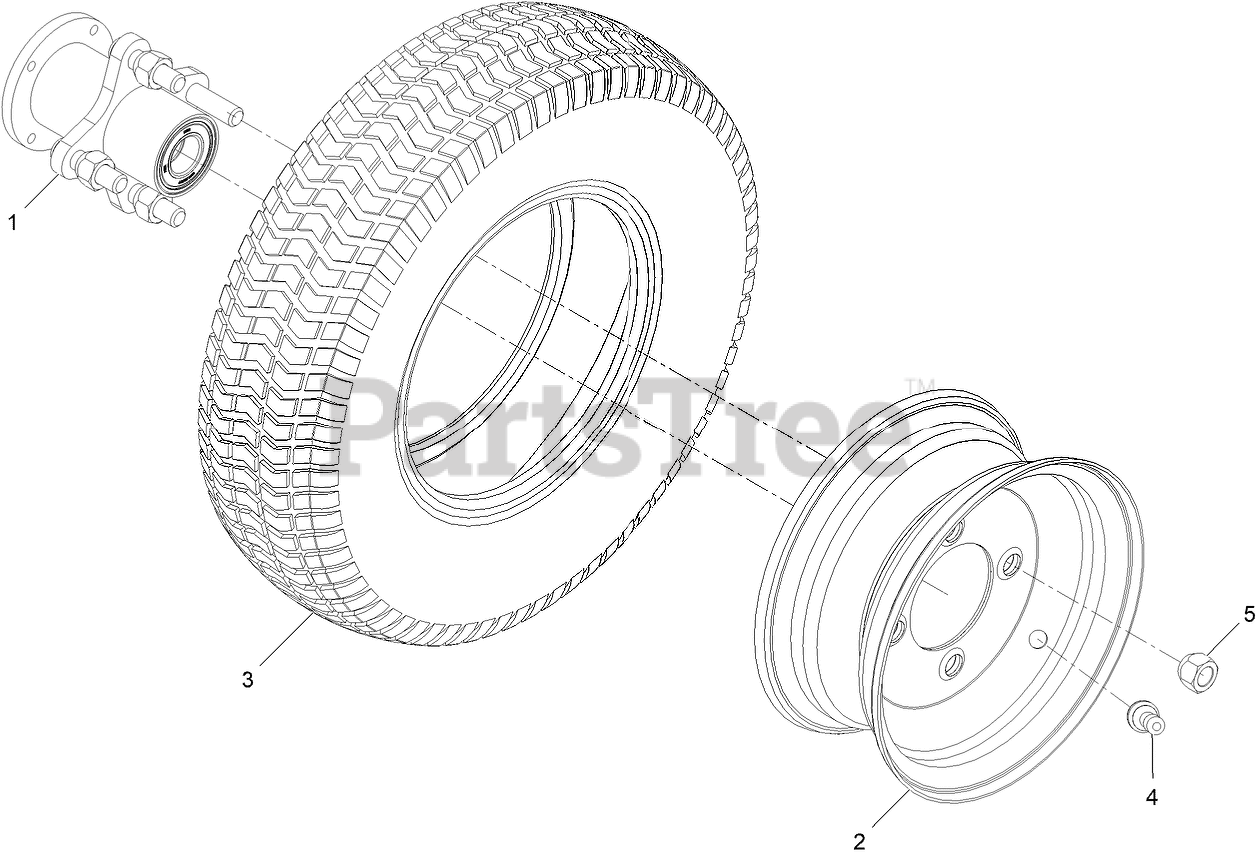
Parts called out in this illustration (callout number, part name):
1	Wheel Hub ASM
2	Rim
3	Tire
4	Stem-Valve
5	NUT-LUG
